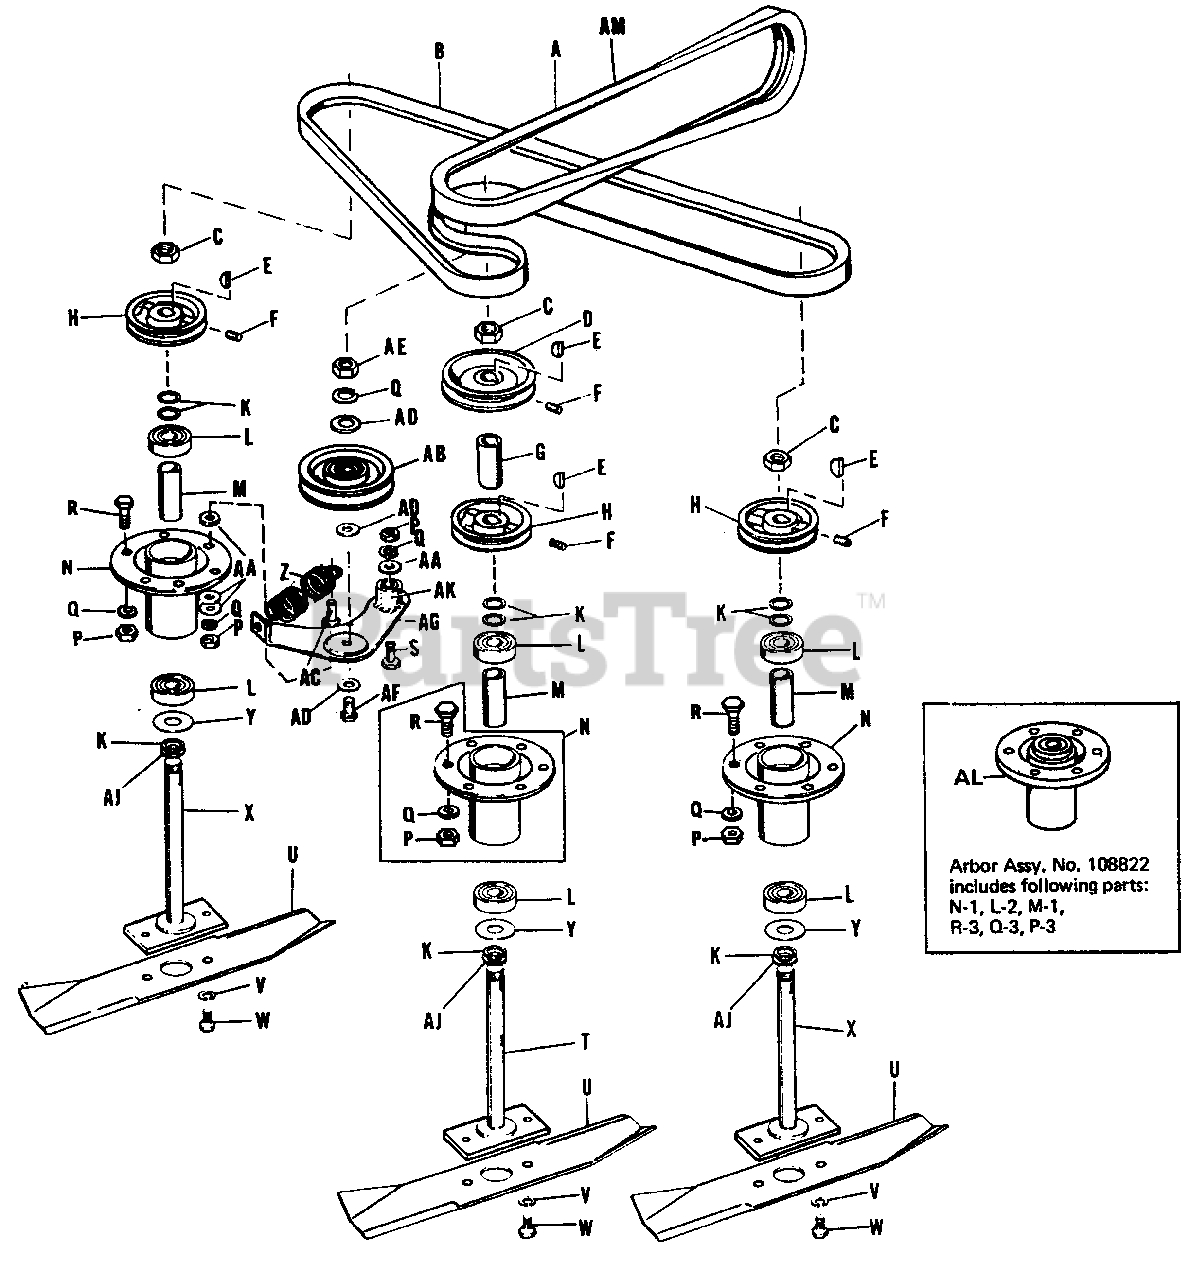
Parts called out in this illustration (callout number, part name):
B	Belt,"V" (Mower Spindle Drive)
C	Hex, Jam Lock Nut,3/4"-16
D	Cross drive Pulley
E	Key, Woodruff, 61
F	Set Screw, 5/16"-18 x 3/8"
N	Arbor Tube Assembly
P	Full Hex, Nut, 3/8"-16
Q	Lock Washer, 3/8"
R	Hex Cap Screw, 3/8"-16 x 3/4" lg.
S	Hex, Cap Screw 3/8"-16 x 1-3/4" lg.
T	Arbor Drive Assembly
U	Knife Blade
V	Lock Washer, 3/8"
W	Hex. Ht. Capscrew, 3/8"-16 x 5/8"
X	Arbor Assembly
AA	Plain Washer, 5/16"
AB	Idler Pulley
AD	Plain Washer, 5/16"
AE	Full Lock Hex. Nut, 3/8"-16
AG	Idler Lever Assembly
AL	Arbor Assembly with Bearings and Hardware
